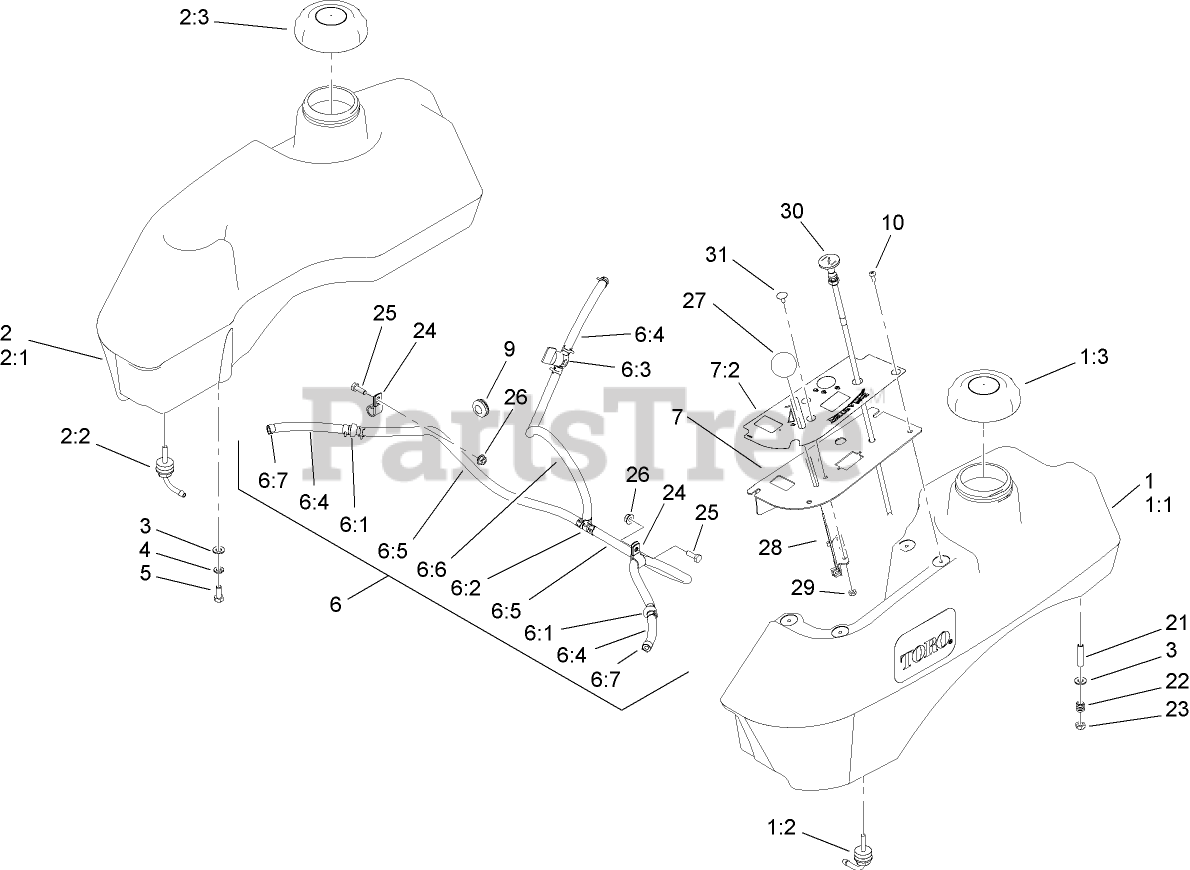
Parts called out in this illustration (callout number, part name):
1	LH FUEL TANK SERVICE KIT
1:1	TANK ASM
1:2	FITTING-FUEL, BULKHEAD
1:3	CAP-FUEL, GAS
2	RH FUEL TANK ASM
2:1	TANK ASM
2:2	FITTING-FUEL, BULKHEAD
2:3	CAP-FUEL, GAS
3	WASHER-PLAIN
4	WASHER-LOCK
5	SCREW-HH
6	FUEL LINE ASM
6:1	VALVE-CHECK, FUEL
6:2	FITTING-TEE, BARBED
6:3	VALVE-FUEL
6:4	HOSE-FUEL
6:5	HOSE-FUEL
6:6	HOSE-FUEL
7	CONTROL PANEL ASM
7:2	DECAL-PANEL, CONTROL
9	GROMMET
22	SPRING-TANK, FUEL
23	NUT-LOCK, NI
24	CLIP-LOOM
25	SCREW-HH
26	NUT-HF
27	KNOB-BALL
28	THROTTLE CABLE ASM
29	NUT-LOCK, NI
30	CONTROL-CHOKE
31	BOLT-CARR
